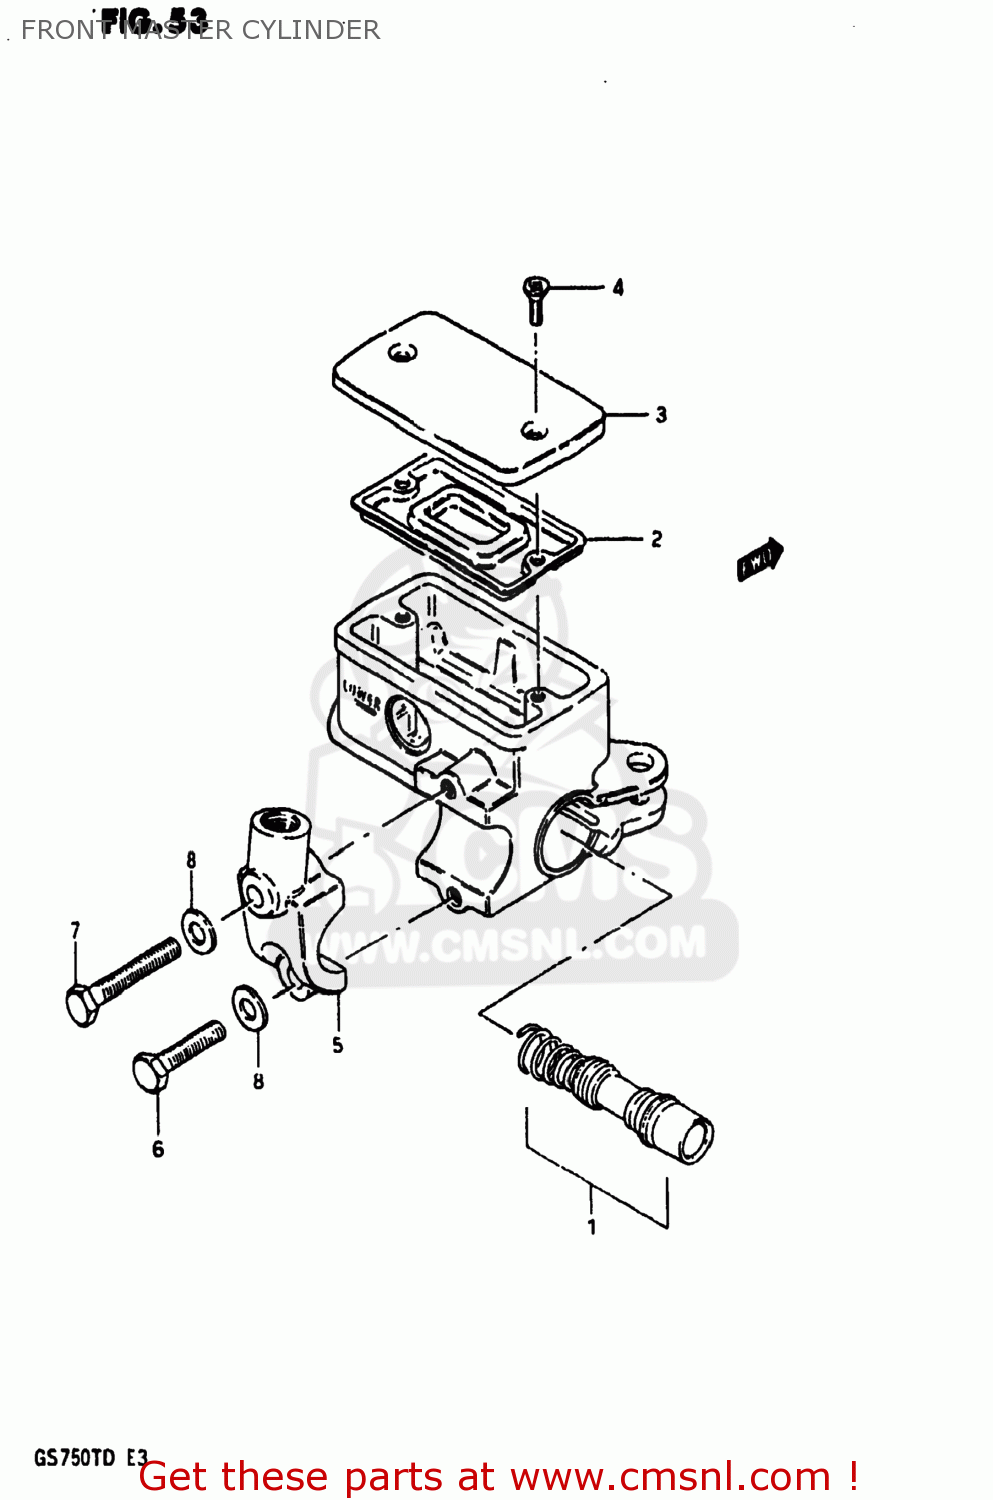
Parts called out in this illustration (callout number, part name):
1	PISTON & CUP SET
2	3
3	CAP
4	SCREW
5	HOLDER
6	BOLT
7	BOLT 6X40
8	WASHER
